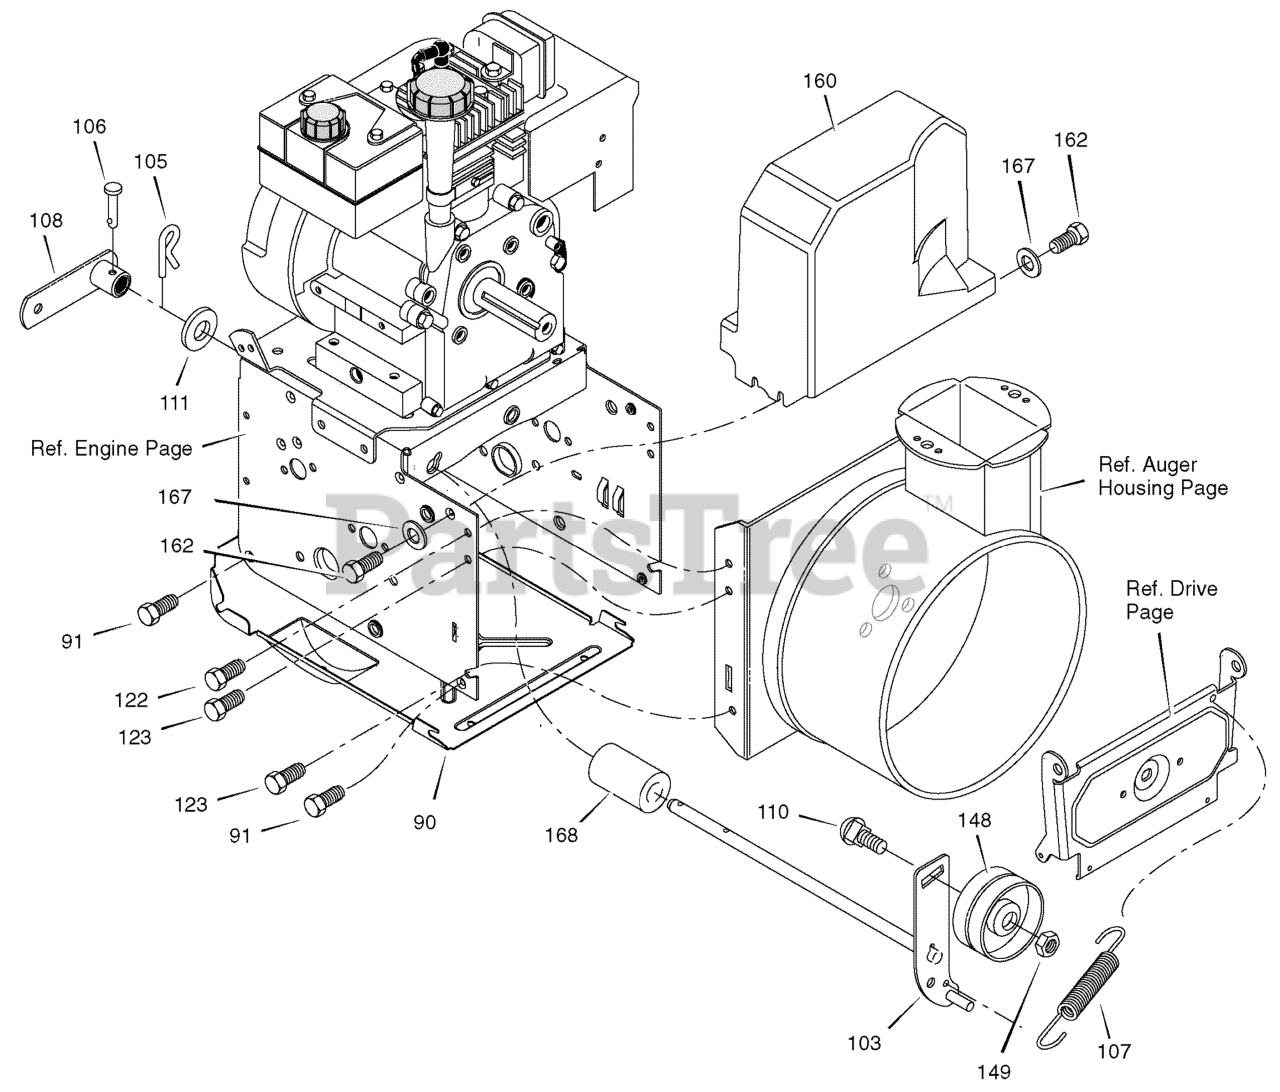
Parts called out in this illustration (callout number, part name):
90	COVER, BOTTOM
91	SCREW, 1/4-20X .63
103	IDLER ASSEMBLY, AUGER
105	PIN, HAIR .38DIAX1.64LG
106	PIN, CLEVIS 3/16" DIA
107	SPRING, TENSION
108	ASSY., SPRING ATTACH
110	BOLT, 3/8-16X1.25 CARR.
111	WASHER, FLAT
122	SCREW, TAP 5/16-18 X .75
123	SCREW, TAP 5/16-18 X .50
148	PULLEY, IDLER
149	NUT, JAM 3/8-16
160	COVER, BELT
162	SCREW, TAP
166	WASHER, FLAT
168	SPACER, AUGER BRACKET
